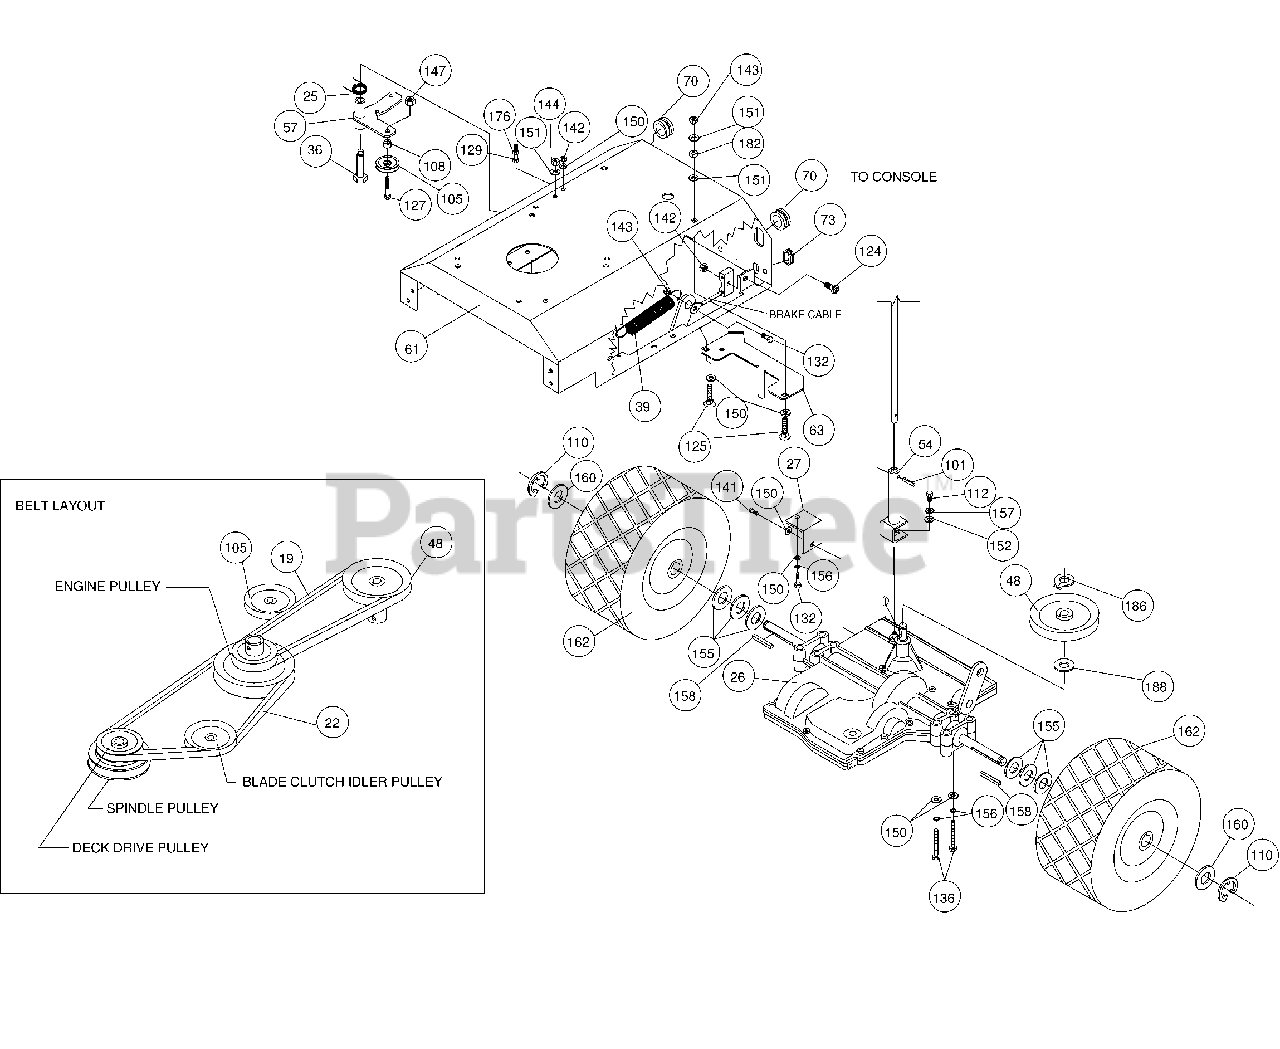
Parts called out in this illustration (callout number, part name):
19	BELT TRANS DRIVE FM
22	BELT BLADE DRIVE FM
25	SPRING TORSION WIRE
26	TRANSAXLE 5SPD FM
27	BRACKET T-AXLE SUPPORT
36	BOLT SHOULDER 1/2” X 2”
39	SPRING BRAKE
48	PULLEY 6.875 OD 4LV GROOVE .625 BORE
54	SHIFT LINKGAGE WA FM
57	BRKT IDLER GRND DRIVE
61	BASE ENGINE W/INSERTS
63	BRACKET BELT GUIDE DRV
70	GROMMET RUBBER 1”
73	GROMMET RUBBER 1.25”
101	ROLL PIN 1/4” X 1.0 IN LONG
105	PULLEY IDLER TENSION
108	TUBE PIVOT IDLER VQ
110	RING SNAP 0.75
112	SCREW CAP 1/4-28X1/2” GR 5
124	BOLT CARR. 1/4-20X1.25”
125	BOLT CARR. 5/16-18X1 1/2”
127	SCREWCAP 3/8-16 X 1 3/4
129	SCREWCAP 1/4"-20 X 2.75"
132	SCREWCAP 5/16-18 X 1.25"
136	SCREW CAP 5/16 - 18 x 2.75
141	SCREW SELF TAP 5/16
142	NUT LOCK 1/4-20 NYLON
143	NUT LOCK 5/16-18 NYLON
144	NUT LOCK 3/8-16 NYLON
147	NUTLOCK 3/8”-16 LW TH ZP
150	WASHER 1/4” FC
151	WASHER 5/16” FC
152	WASHER 1/4 SAE
155	WASHER 3/4 FC
156	WASHER LOCK 5/16 SPLIT
157	WASHER LOCK 1/4” EXT.
158	KEY 3/16 x 2 1/8
160	WASHER 3/4 THIN
162	WHEEL AND TIRE 13”
176	NUT JAM 1/4-20
182	NUT JAM 5/16
186	RING SNAP 5/8 T.A.
188	WASHER 3/4"
